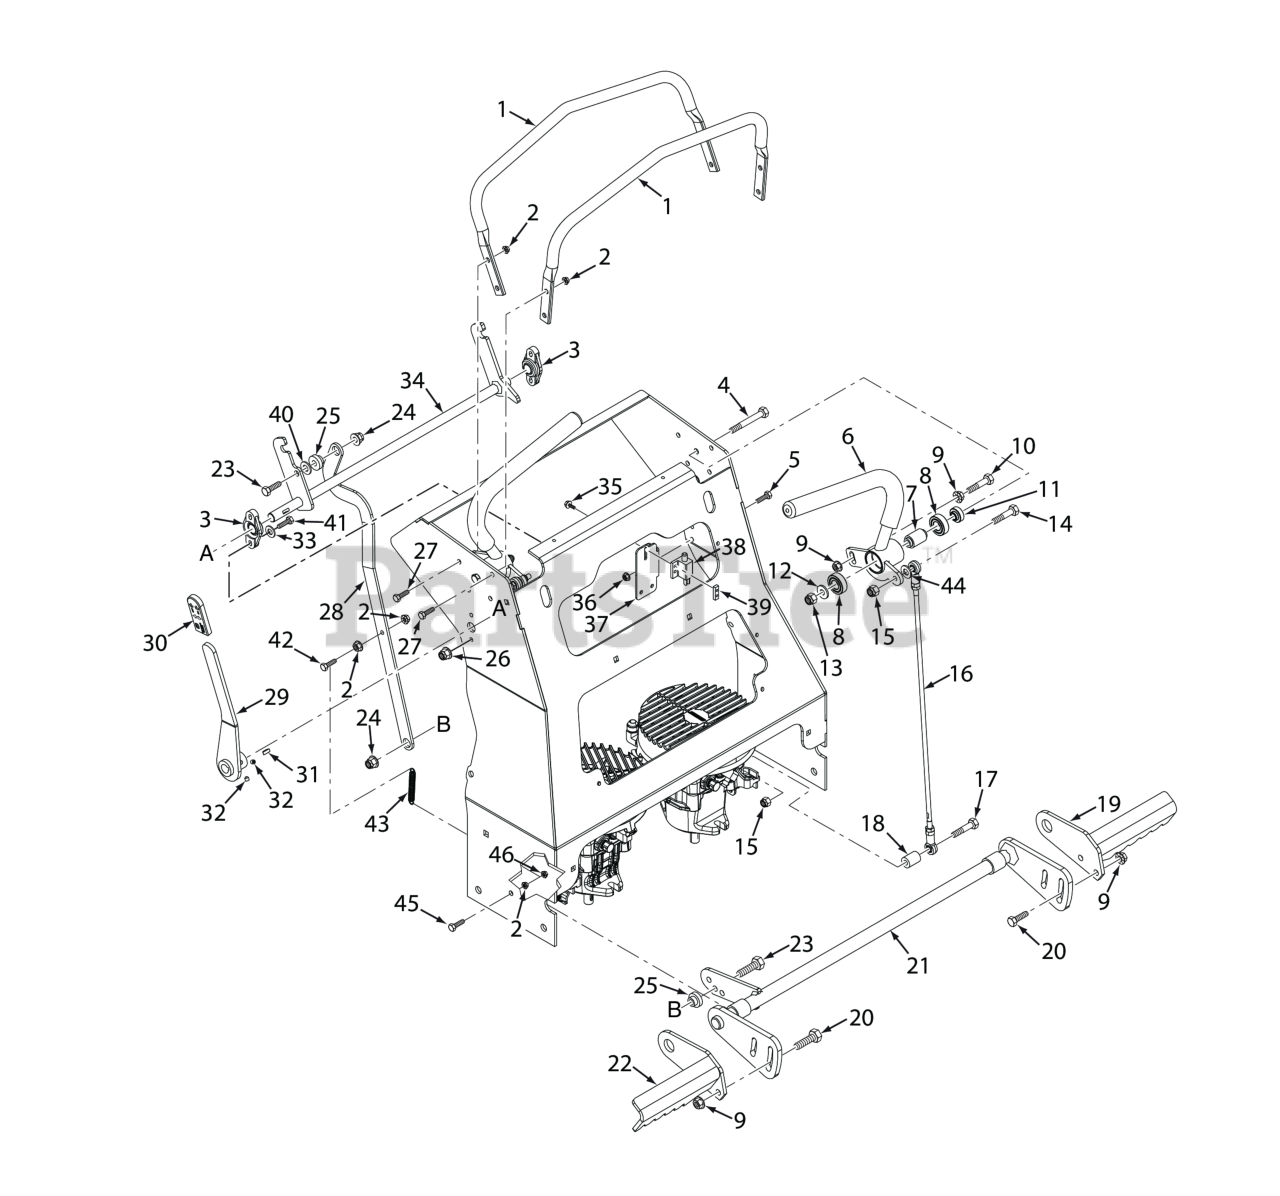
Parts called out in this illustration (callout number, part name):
1	Reference Bar
2	Nut, Serrated Flange 5/16-18 (Right Front Engine Mounting, Briggs and Kohler Only)
3	Bearing
4	Capscrew, Hex Head 3/8-16 x 3.25"
5	BOLT, HEX HEAD, 1/4-20 X 3/4 GR.5
6	Handlebar Assy., LH
7	Spacer, Bearing
8	BEARINGS, BALL, NEUTRAL RETURN
9	NUT, 3/8-16 SERRATED FLANGE HEX HEAD
10	Capscrew, Hex Head 3/8-16 x 2.0"
11	Spacer, Controls
12	Flatwasher, 3/8 (.391 x .938 x .105 HD) Grade 8
13	HEX NUT, ELASTIC STOP LOCK, 3/8-16
14	Bolt, 5/16 - 18 x 1 - 1/4" Hex Head
15	HEX NUT, ELASTIC STOP LOCK, 5/16-18
16	Linkage Assy., Steering
17	Hex Head Socket, 5/16-18 x 1" (36)
18	Spacer (excludes SVRII-36A)
19	Brake Paddle Weldment, RH (36)
20	Carriage Bolt, 3/8-16 x 1.0"
21	Bellcrank Weldment, Brake (32/36)
22	Brake Paddle Weldment, LH
23	Bolt, Hex Head 3/8-16 x 1-1/4", Kawasaki FX / FS
24	Nut, Flange Elastic Stop Nut, 3/8-16
25	BUSHING, BRONZE - .376 ID X .627 OD
26	Nut, Flanged Elastic Stop 1/4-20
27	BOLT, SERRATED FLANGE HEX HEAD 5/16-18 X 3/4"
28	Link, Brank Engage (36)
29	Brake Lever Assy. - SVRII (Incl. #30)
30	Grip, Parking Brake
31	KEY, 3/16 X 3/16 X 1-1/2
32	Set Screw 1/4-20 x 1/4"
33	Flatwasher, 1/4 (.281 x .625 x .065)
34	Lock Weldment, Neutral
35	Screw, Hex-Slotted Washer Head #10 32 x 3/4"
36	NUT, 1/4-20 SERRATED FLANGE HEX HEAD
37	Bracket, Neutral Switch
38	Switch, Interlock (see below)
39	Plate, Threaded
40	Flatwasher, 3/8" Special (.391 x .938 x .105)
41	Capscrew, Hex Head 1/4-20 x 1"
42	Bolt, Hex Head 5/16-18 x 1-1/2" (Right Front Engine Mounting, Briggs and Kohler Only)
43	Spring, Deck Lift
44	Flatwasher, 5/16-.344 x .688 x .065 (48V / 52V)
45	Bolt, Hex Head 5/16-18 x 1-1/2" (Right Front Engine Mounting, Briggs and Kohler Only)
46	Nut, Serrated Flange 5/16-18 (Right Front Engine Mounting, Briggs and Kohler Only)
